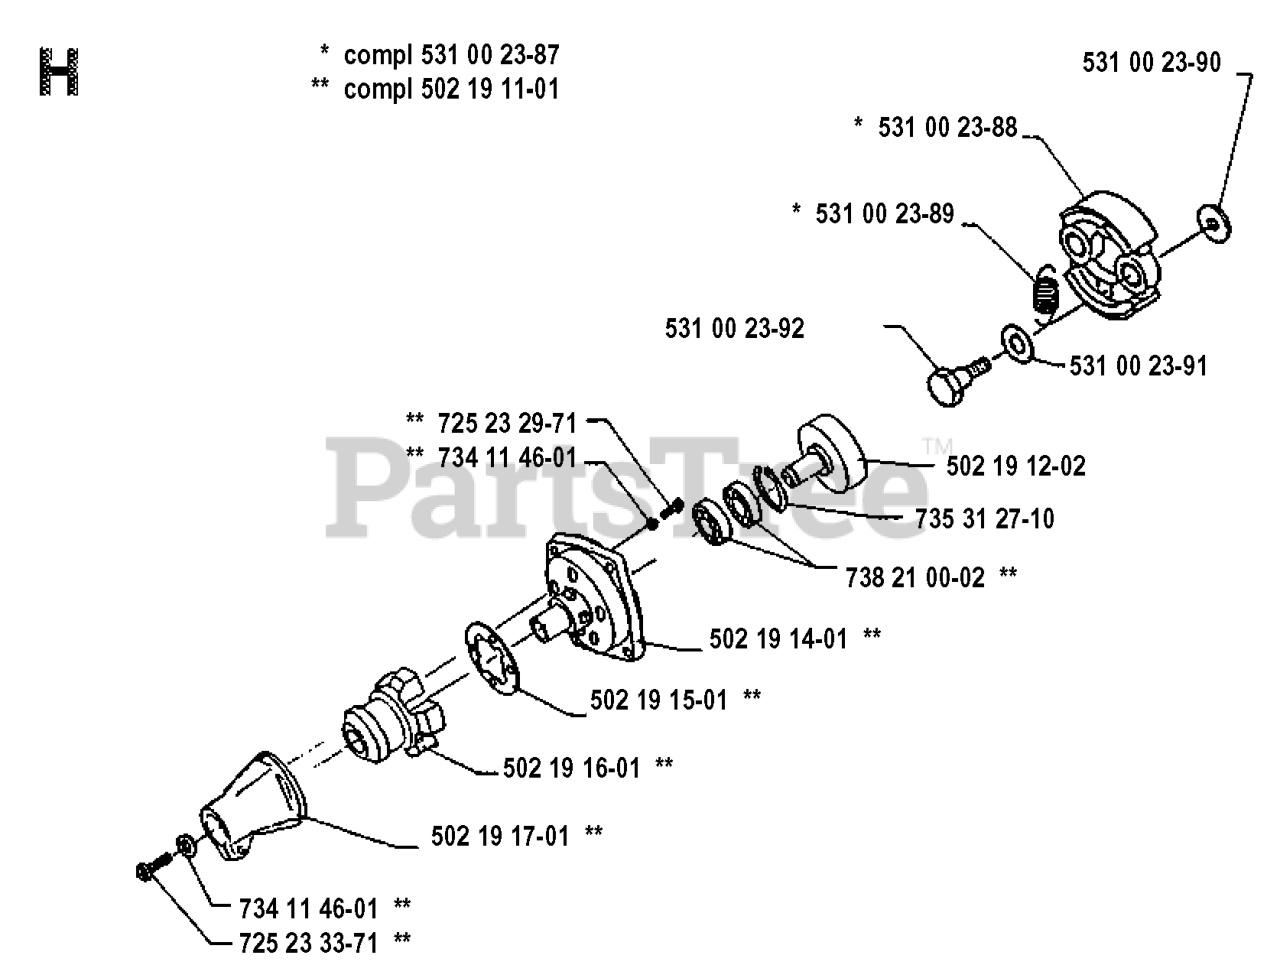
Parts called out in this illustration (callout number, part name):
1	DECK 42"
2	RP BOLT 5/16-18 X3/4 ZN/YEL GR
3	BRKT ASM SWAY BAR
4	BRKT DECK SW BAR
5	RETAINER-SPRNG RB
6	REAR SUSP ARM
8	BLADE BOLT
9	LOCKWASHER
10	WASHER.BLADE
11	BLADE.42".MULCH
12	BEARING.BALL.#6204.(MANDREL)
13	SHAFT ASM VENT
14	HOUSING.MANDREL.VENTED (MACHD)
16	STRIPPER
17	BOLT CARRIAGE
18	BOLT
19	BOLT SHD 5/16-18
20	BAFFLE
21	LOCKNUT
22	STIFFENER BRACKET
23	DEFLECTOR BRACKET
24	CAP-SLEEVE LT
25	SPRING TORSION
26	NUT PUSH M
27	SHIELD.DEFLECTOR.MOWER.42".BLK
28	Washer 11/32 x 5/8 x 16 Ga SD
29	ROD.HINGE
30	SCREW
31	WASHER
32	PULLEY/MANDREL
33	NUT
35	FASTENER.XMAS.TREE
36	FLAT IDLER PULLEY
37	WASHER
38	IDLER SPRING SPACER
44	GUARD MANDREL LH BLACK
46	SCREW.1/4-20X5/8
54	HARDENED WASHER
55	IDLER ARM
56	SPACER RETAINER
59	GUARD, BELT
61	SPRING EXTENSION
68	V-BELT TRIPATH
84	KEEPER.BELT.IDLER
85	BOLT
90	BOLT
91	BRACKET LH (A)
92	NUT
93	Washer 1 17/32 X 7/8 X 16 Ga
94	NOSE ROLLER
95	BRACKET RH (B)
101	COVER MULCH 42"
102	SCREW
104	LOCKWASHER #10
105	LATCH ASSEMBLY
106	WELDNUT
111	BRACKET WHEEL GAUGE LH 42" DK
112	BRACKET WHEEL GAUGE RH 42" DK
113	SCREW.THDROL.5/16-18X3/4.TTY
114	NUT
115	BOLT.CARR.5/16-18X1/2
116	BOLT, SHOULDER
117	WHEEL GAGE DONUT
118	LOCKNUT
119	WASHER.5/16.FLAT.STE.STD.
121	BRACKET.EXTRUDED.GAGE.WHEEL
125	Pin Cotter 1/4 x 1 Plated
128	WASHER FELT
129	WASHER
131	BOLT D
132	Washer 13/32 x 1-3/8 x 13 Ga.
